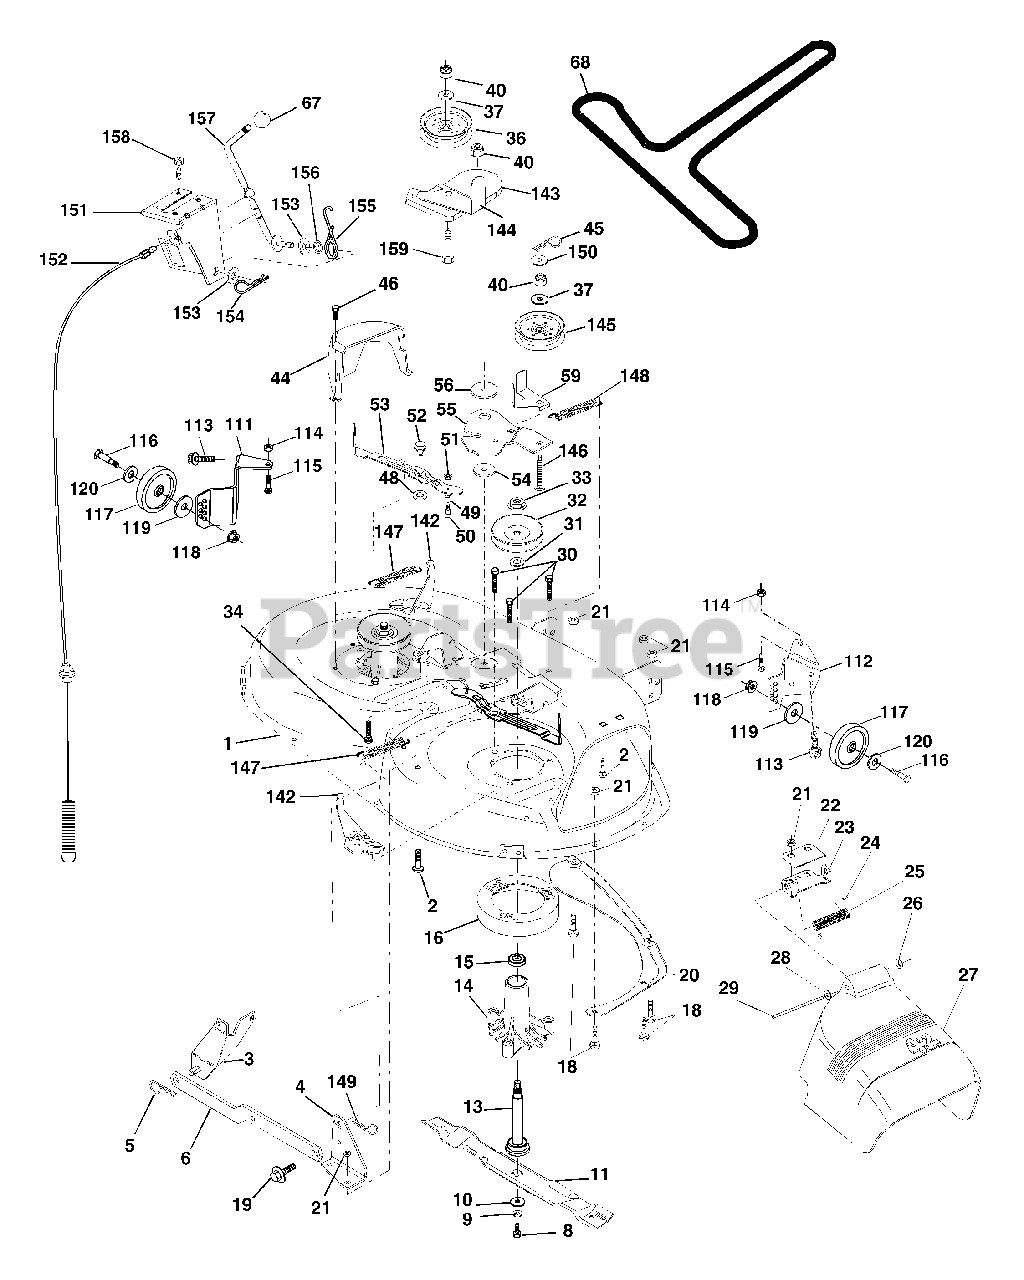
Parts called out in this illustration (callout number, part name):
1	Mower Deck Assembly, 42"
2	Bolt
3	Bracket Asm Fr. Sway Bar 3/42
4	Bracket Asm Deck 42" Sway Bar
5	Retainer Spring
6	Bar Sway Deck
8	Bolt 3/8-24 x 25 Grade 8 patched
9	Washer, Lock
10	Washer, Hardened
11	Blade
13	Shaft Assembly, Mandrel, Vented
14	Housing, Mandrel, Vented
15	Bearing, Ball, Mandrel
16	Stripper, Vented Mower Deck
18	Bolt, Carriage 5/16-18 x 5/8
19	Bolt, Shoulder
20	Baffle, Vortex
21	Nut
22	Stiffener Bracket
23	Bracket, Deflector Mower 42"
24	Cap, Sleeve 80 x 112 Blk Mower
25	Spring, Torsion, Deflector 2 52
26	Nut, Push Phos & Oil
27	Shield, Deflector 42" Blk
28	Washer 11/32 x 5/8 x 16 Gauge
29	Rod, Hinge 42" 6 75 W/G
30	Screw Thdrol Washer Head
31	Washer, Spacer Mower Vented
32	Pulley, Mandrel
33	Nut, Toplock Flange
34	Bolt
36	Pulley, Idler, Flat
37	Washer 13/32 x 13/16 x 16 Gauge
40	Nut
44	Guard, Mandrel, LH
45	Retainer
46	Screw, Thdrol 1/4-20 x 5/8 T
48	Washer, Hardened
49	Roller Assembly, Cam Follower
50	Bolt, Shoulder #10-24 Grade 5
51	Locknut
52	Bolt, Shoulder 5/16-18 UNC
53	Arm Assembly, Pad, Brake
54	Washer, Hardened
55	Arm, Idler
56	Spacer, Retainer
59	Guard TUV Idler
67	Knob
68	V-Belt, 42" Mower
111	Bracket, Gauge, Wheel LH
112	Bracket, Gauge, Wheel RH
113	Screw Tapping 3/8-16 x .625
114	Nut, Keps 5/16 - 18 UNC
115	Bolt, Carriage 5/16-18 x 5/8
116	Bolt, Shoulder
117	Wheel, Gauge
118	Nut Centerlock 3/8-16
119	Washer 3/8 x 7/8 x 14 Ga.
120	Washer 17/32 x 15/16 x 12 Ga.
142	Arm Spring Brake Mower
143	Bracket Arm Idler 42"
144	Keeper Belt 42" Clutch Cable
145	Pulley Idler Flat
146	Bolt Carriage Idler
147	Spring Extension
148	Spring Return Idler
149	Retainer Spring Yellow
150	Washer 9/32 x 3/4 x 16 Ga.
151	Bracket Clutch Cable
152	Clutch Cable 42"
153	Washer Flat 3/8" Type B
154	Spring Retainer
155	Spring Retention LVR CLTCH CAB
156	Spacer Clutch Cable
157	Rod Clutch Cable 3/8"
158	Screw Hex Thd Cut 1/4-20 x 5/8
159	Bolt Rdhd Sqn 3/8-16 UNC x 1-3/4
